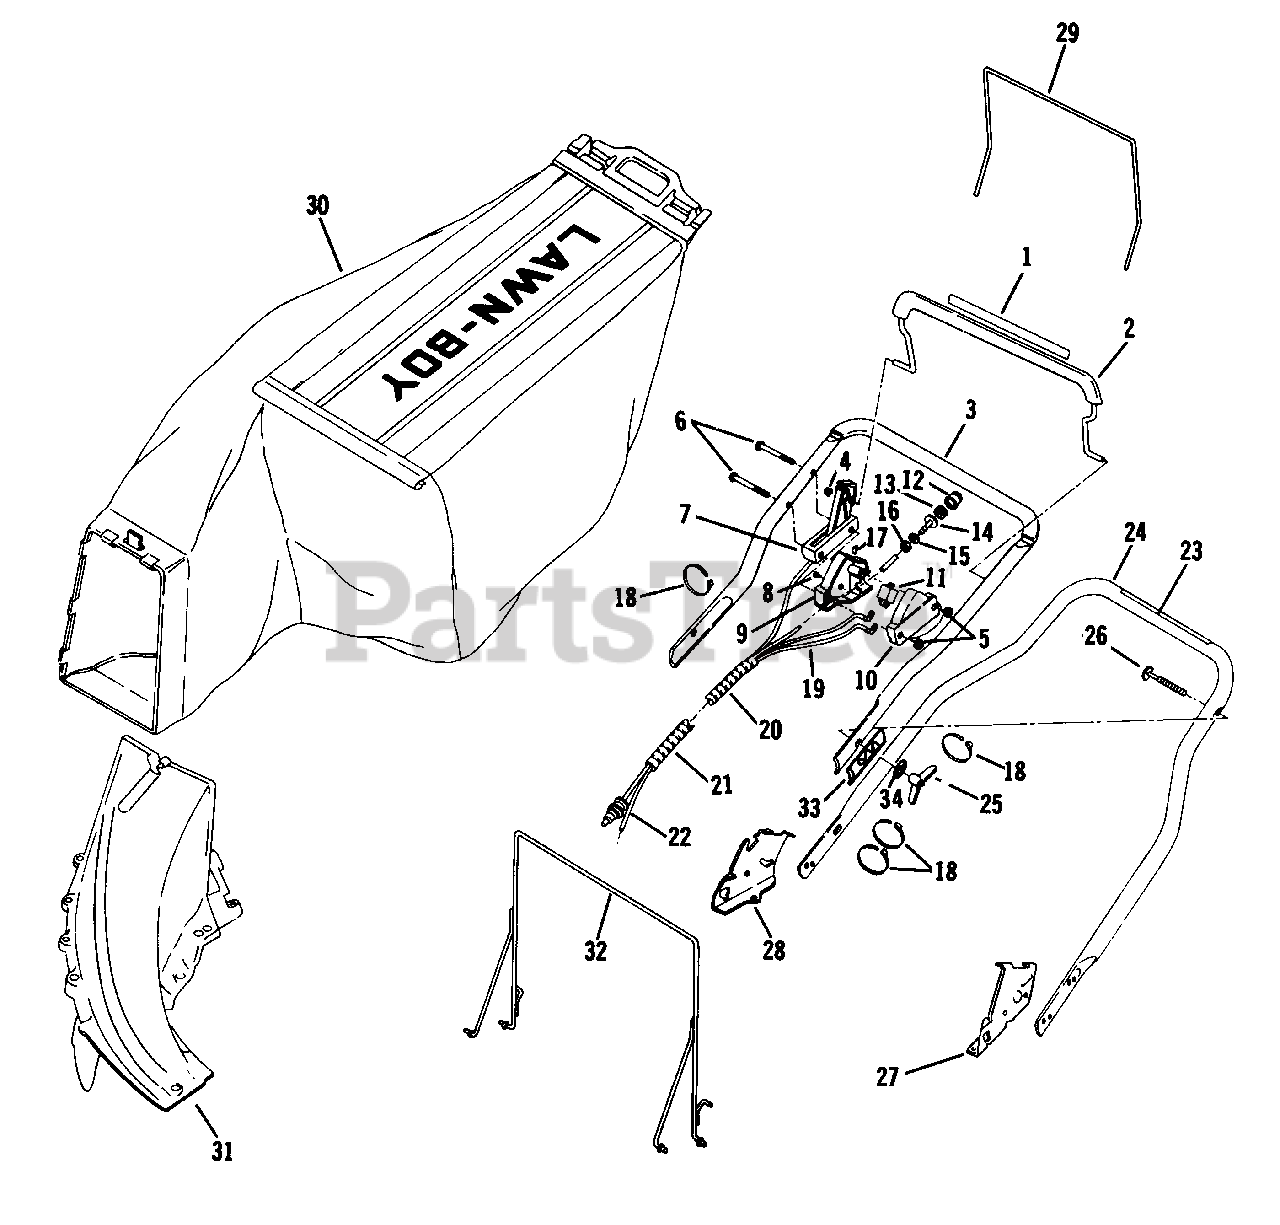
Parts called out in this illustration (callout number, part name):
1	Decal-Blade Control
2	Control Lever Assembly
3	Top Handle and Grip Assembly
4	Pushnut
5	Nut-Hex-Centerlock
6	Screw
7	B.B.C. Control Assembly
8	Screw
9	Console-R.H.
10	Console-L.H.
11	Switch Assembly
12	Primer Bulb
13	Filter
14	Primer Base
15	Washer
16	Locknut
17	Decal
18	Tie Strap
19	Wire Harness Assembly
20	Spiral Tubing
21	Spiral Tubing
22	Tubing
23	Decal-Starting Inst.
24	Handle-Bottom
25	Knob
26	Screw-Folding Handle
27	Handle Bracket-L.H.
28	Handle Bracket-R.H.
29	Hanger-Rear
30	Bag Assembly
31	Chute Assembly
32	Hanger Ass'y.-Front
33	Bracket-Rear Hanger
34	Washer
